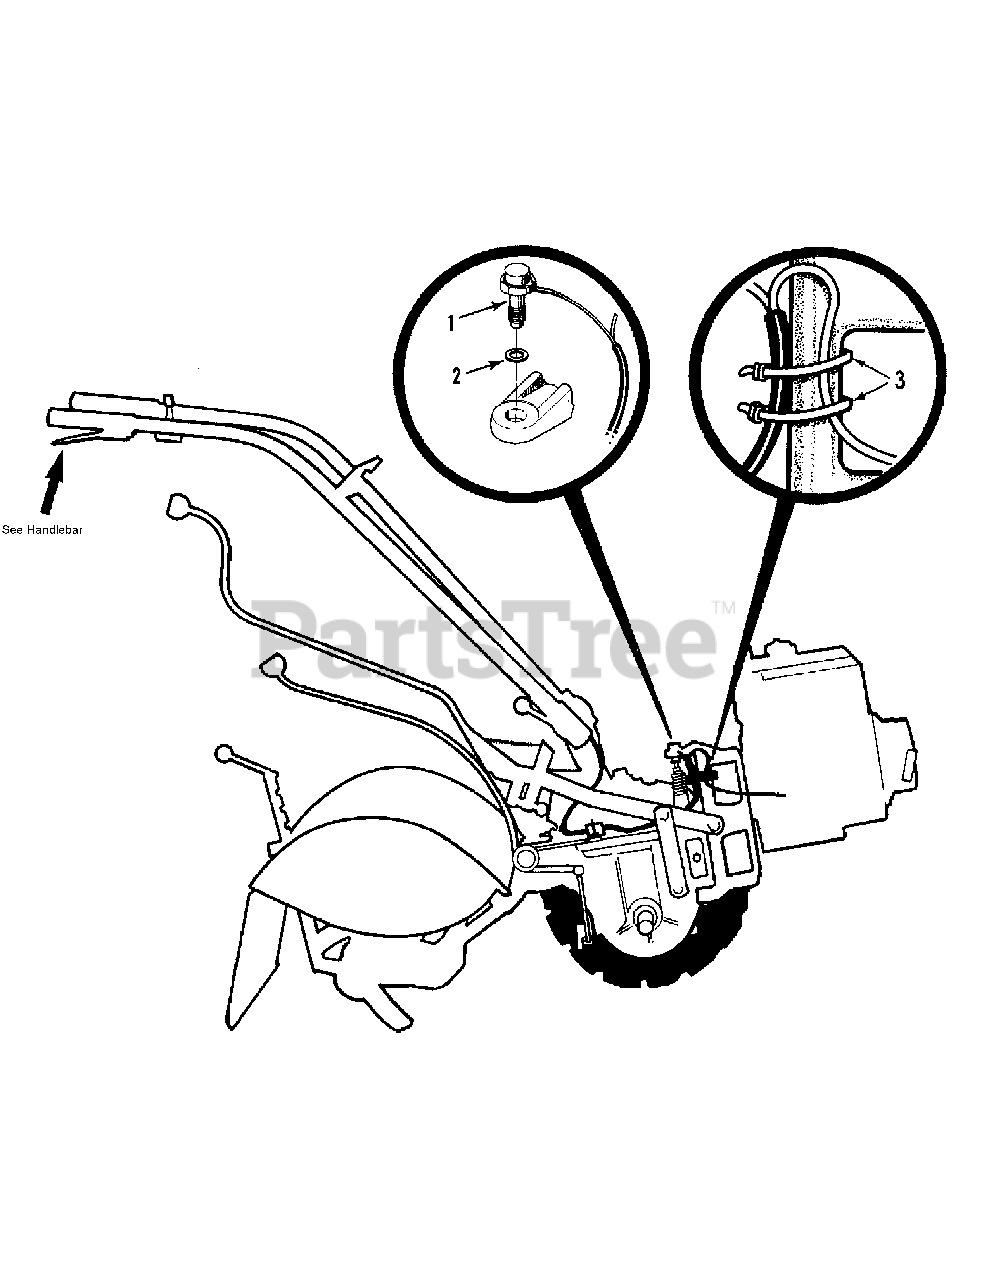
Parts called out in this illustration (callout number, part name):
1	Engine Wire Harness Ass'y.-forward interlock system (Incl. 1 red, 1 black wire, plug connector, neutral switch & PVC tubing.)
2	Internal L-Washer 9/16"
3	Tie-plastic
